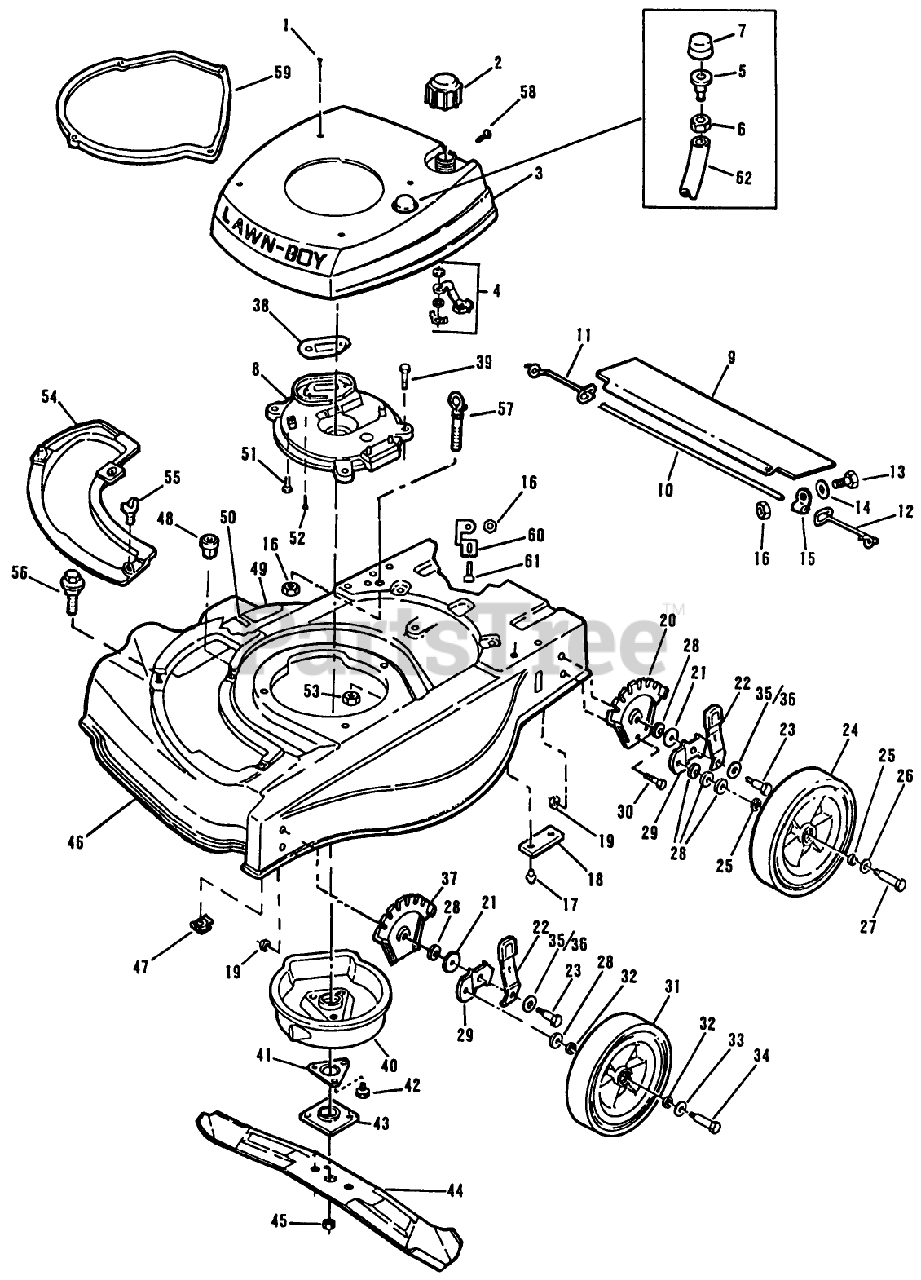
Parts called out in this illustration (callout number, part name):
1	SCREW LAWRENCE
2	FUEL CAP & INSERT
3	SHROUD,TANK&VAVLE
6	LOCKNUT S
7	P-BULB LAV-RUB
8	PLATE,MUFFLER F
10	ROD T/SHIELD ADV WIRE
11	SPRING;TRAILING SHIELD RH
12	SPRIG T/SHLD ASOC
14	WASHER F
15	CLAMP ROD KMC
16	LOCKNUT E
17	SCREW
19	LOCKNUT
21	WASHER
22	KNOB&SPRING FORMCO
23	BOLT
25	WASHER
26	SPACER
28	WASHER WROUGHT
31	WHEEL & TIRE KIT
32	WASHER
33	SPACER
34	BOLT WHEEL
35	WASHER
36	WASHER
37	PLATE HGT ADJ TRO
38	GASKET-EXHAUST F
39	SCREW-HH
41	SUPPORT F
42	SCREW
43	PLATE AND COLLAR ASM
45	NUT-BLADE
47	NUT-CAGE
52	SCREW V
53	NUT-LOCK F
54	Cover Plate
55	WING SCREW LAWRE
57	BOLT-EYE
58	SCREW S
62	TUBING-PRIMER POLY
